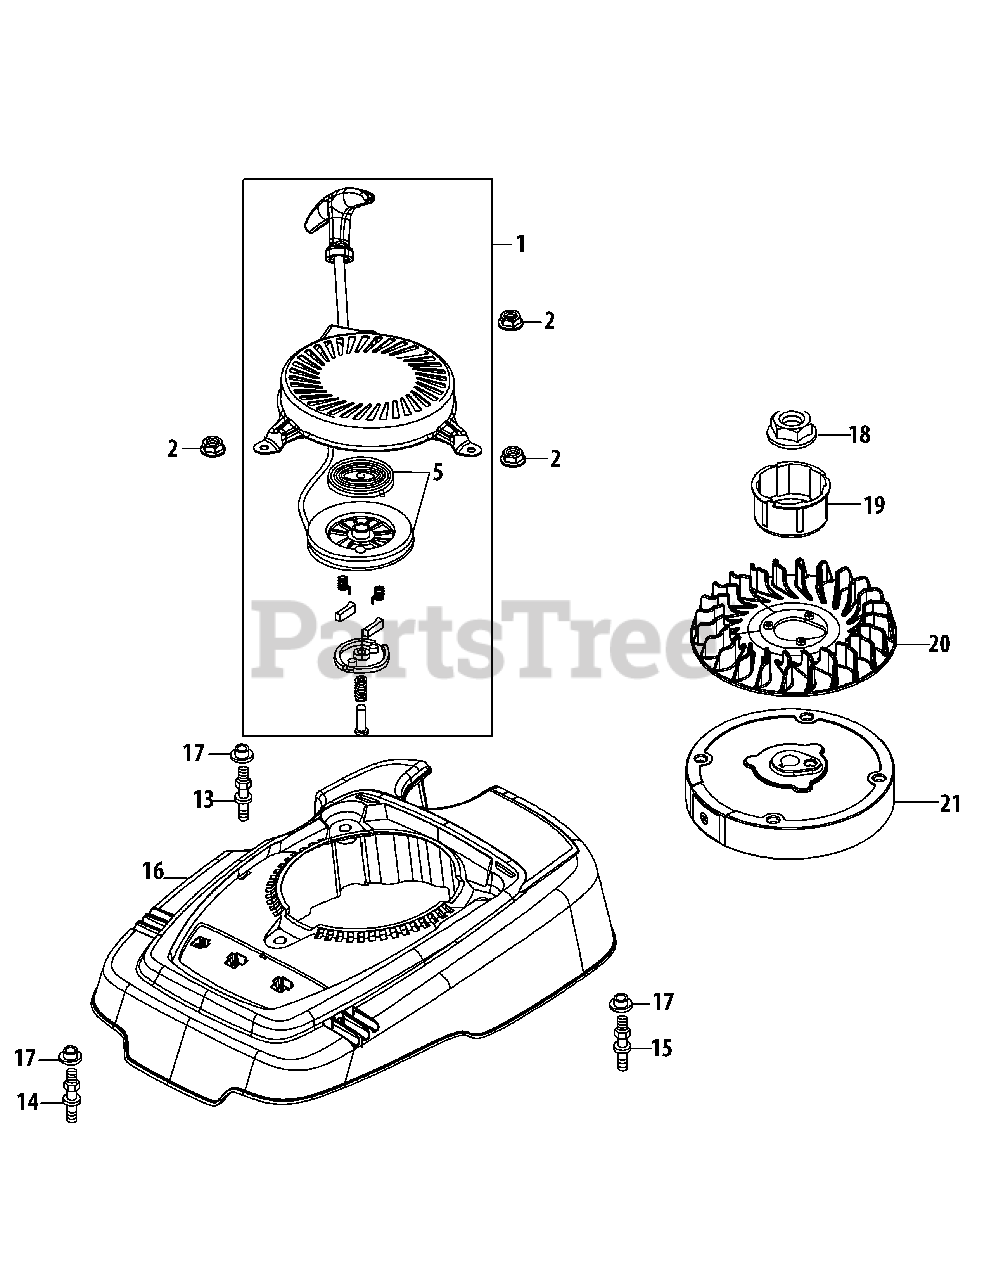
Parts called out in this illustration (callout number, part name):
1	Recoil Starter Assembly
2	Nut M6
5	Recoil Spring
13	Shroud Stud M6×85-48
14	Shroud Stud M6×87-51.5
15	Shroud Stud M6×79
16	M6 Inner Shroud
17	Spacer
18	Nut M14×1.5
19	Starter Cup
20	Cooling Fan
21	Flywheel
